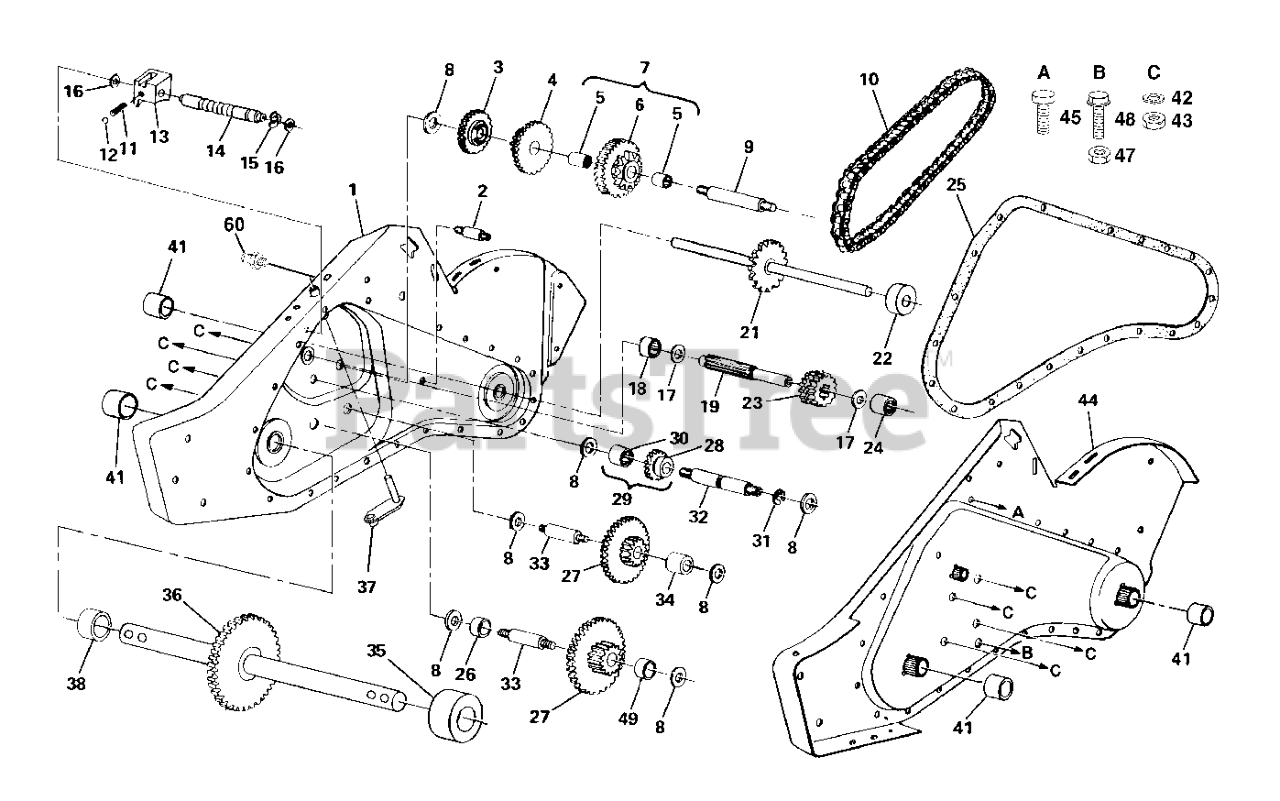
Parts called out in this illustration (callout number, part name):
1	GEARCASE ASM.RH.W/BEARING 2002
2	SPACER.GEARCASE
3	GEAR.REVERSE.8HP
5	BEARING.NEEDLE.CRT
6	SPROCKET ASMBLY, TINE
7	SPROCKET ASMBLY W/BEARINGS
9	SHAFT.REDUCTION.TILLER
10	CHAIN.ROLLER.TILLER
11	SPRING-SHIFT CRT
12	STEEL BALL KIT
13	SHIFT FORK TI
14	SHAFT.SHIFT.1.00 PINION
16	WASHER, SEAL (2 2)
17	THRUST WASHER
18	BEARING TI
19	SHAFT INPUT
21	SHAFT TINE CRT
22	SPACER 1.008X1-3/4X.645
23	GEAR.PINION
24	NEEDLE BRNG LT
25	RP GASKET, GEARCASE
27	GEAR, CLUSTER CRT
28	REVERSE GEAR
29	GEAR ASMBLY, REVERSE IDLER
30	NEEDLE BEARING TI
32	SHAFT, REVERSE IDLER
33	SHAFT, REDUCTION
34	SPACER.765 X 1.12 X .380.
35	SPACER, GROUND DRIVE RH
36	SHAFT ASSY CRT
37	BRACKET ASM.SHIFT.CRT
38	SPACER, GROUND DRIVE
41	SEAL ASM, OIL
42	LOCKWASHER
43	NUT.ASF.HEX.7/16
44	GEARCASE ASM.LH.W/BEARING 2002
45	SCREW
48	SCREW 5/16-18X4
60	FITTING.GREASE.TAPERED
